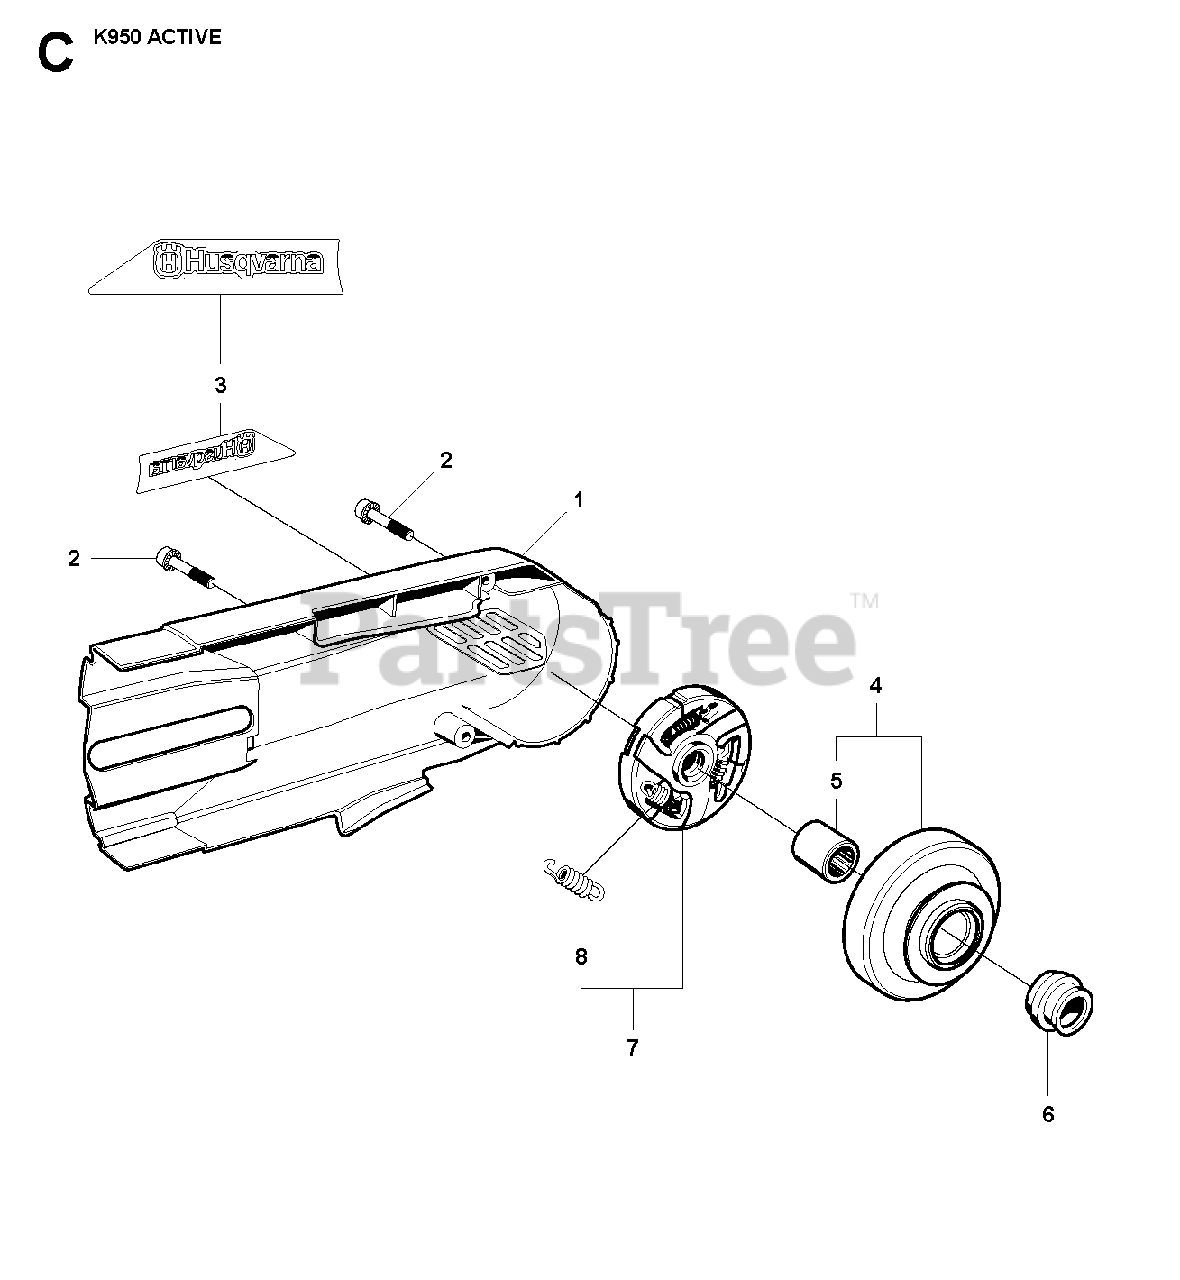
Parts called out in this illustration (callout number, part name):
2	SCREW IHSCFMO
4	GEAR WHEEL ASSY"12"", 14"". Incl. 5"
4	GEAR WHEEL ASSY"16"". Incl. 5"
5	NEEDLE BEARING
6	SPACING SLEEVE
7	CLUTCH ASSYIncl. 8
8	CLUTCH SPRING
